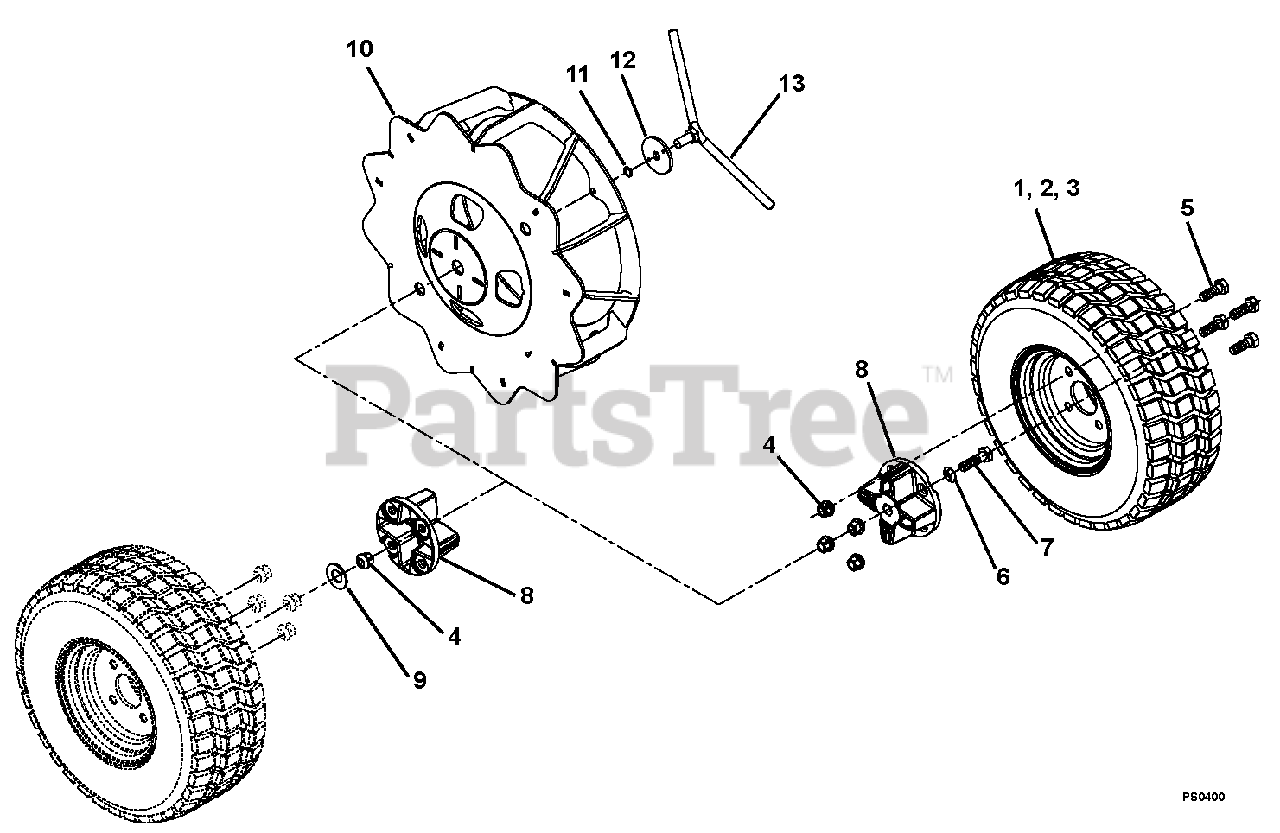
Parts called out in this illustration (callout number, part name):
1	Wheel, Disc
3	Tube, Tire
5	Bolt, Hex D961 M14 x 1. 5 x 40
6	Washer, Spring D74361C M14
7	Bolt, Hex D960 M14 x 1. 5 x 40
8	Driving Flange
9	Washer, Spring D2093B 45 x 22.4
10	Cage Wheel
13	Handle Screw
